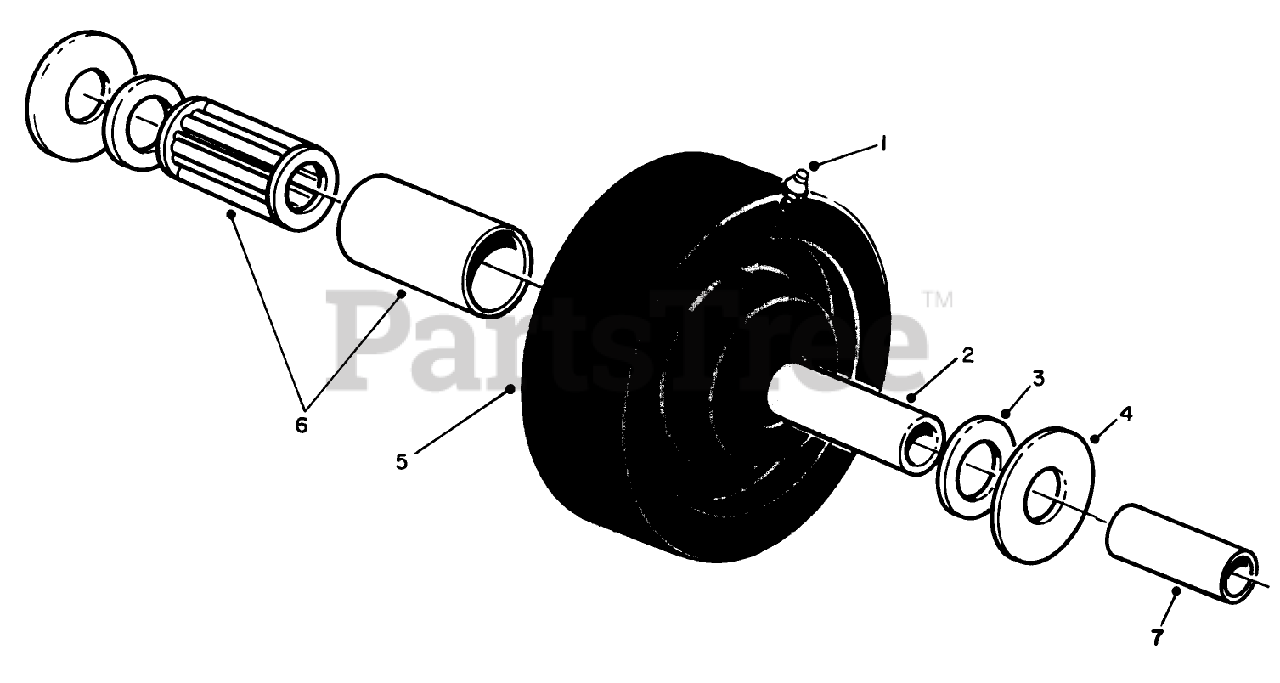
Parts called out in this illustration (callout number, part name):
1	FITTING-GREASE
2	SPANNER BUSHING
3	BEARING RETAINER
4	THRUST WASHER
5	WHEEL
6	ROLLER BEARING
7	SPANNER-TIRE
